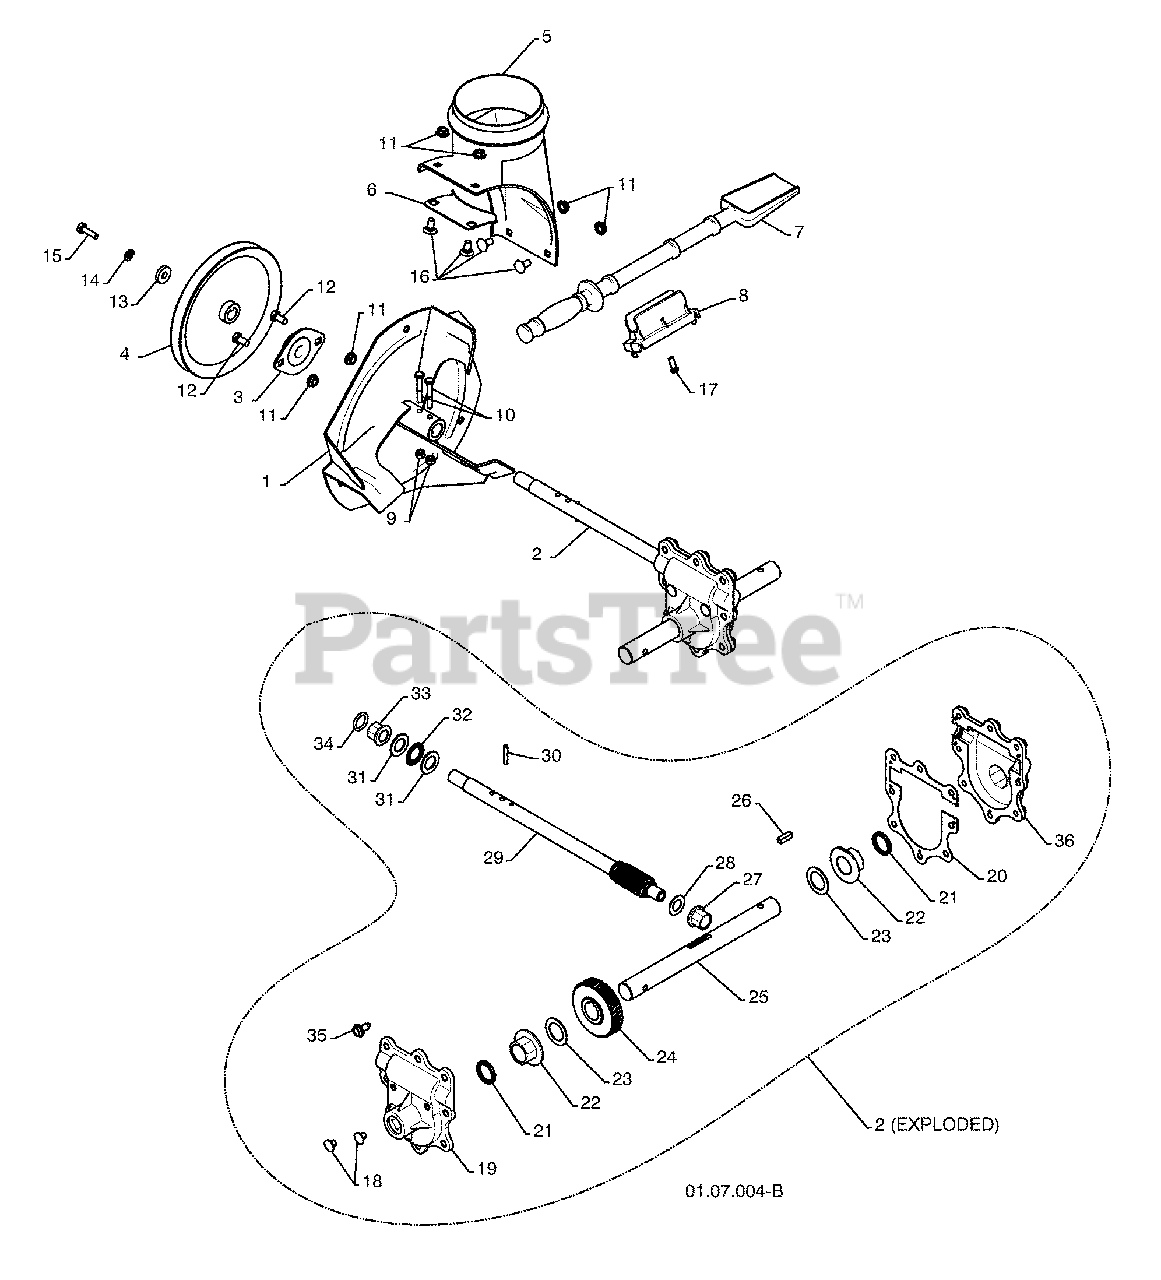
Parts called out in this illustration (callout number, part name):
1	IMPELLER
2	GEARBOX ASSEMBLY
4	IMPELLER PULLEY
5	DISCHARGE BASE
6	CORNER BRACKET
7	CLEAN OUT TOOL
9	NUT 1/4--20
10	SCREW 1/4--20 X .625
11	NUT 5/16--18
12	SCREW 5/16--18 X .625
14	LOCKWASHER 5/16
15	SCREW 5/16--18 X 1.00
16	CARRIAGE BOLT
17	SCREW 13--16 X .625
18	PLUG
19	GEARBOX COVER RH
20	GASKET
21	SEAL
22	BEARING
23	THRUST WASHER 1.00
24	WORM GEAR
25	AUGER SHAFT
26	SQUARE KEY
27	BEARING
28	THRUST WASHER
29	IMPELLER SHAFT
30	ROLL PIN
31	THRUST WASHER
32	THRUST BEARING
35	SCREW 5/16--18 X .750
36	GEARBOX COVER LH
